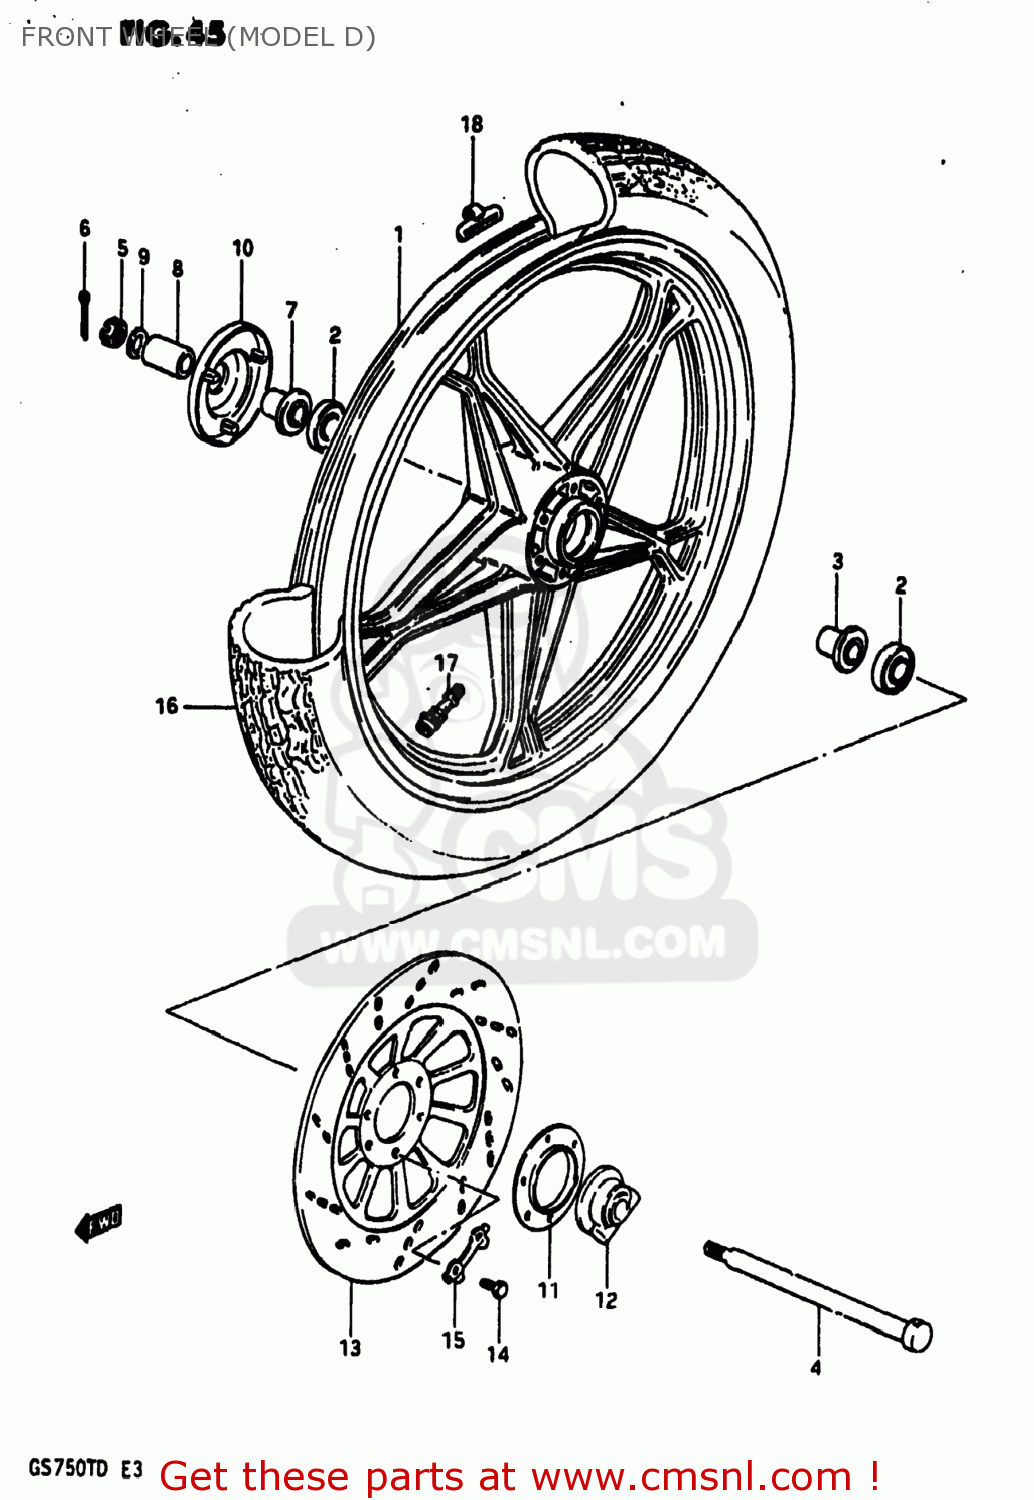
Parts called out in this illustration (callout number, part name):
1	CASTING WHEEL,FRONT 2.15
2	BEARING
3	SPACER,FR HUB BEARING
4	AXLE,FRONT
5	NUT 12MM
6	COTTER PIN
7	SPACER,FR AXLE,R
8	SPACER(15X22X30)
9	WASHER
10	COVER,FR HUB,R
11	DUST SEAL,SPEEDOMETER GEAR BOX
12	BOX ASSEMBLY,SPEEDOMETER GEAR
13	DISC,BRAKE
14	BOLT(8X25)
15	WASHER
16	TIRE,FRONT
17	VALVE ASSEMBLY,WHEEL RIM,J
18	BALANCER,WHEEL
